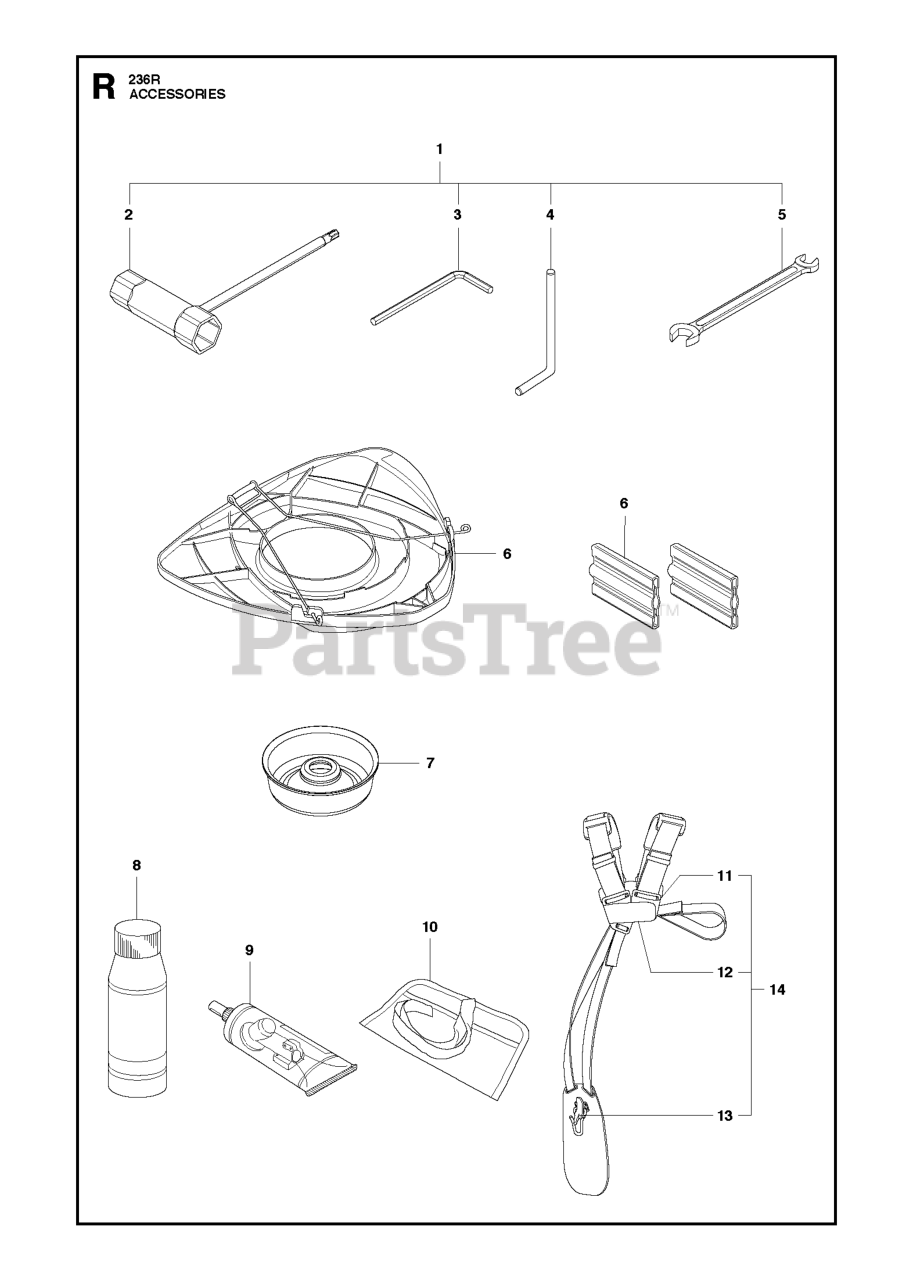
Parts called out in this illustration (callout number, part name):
5	WRENCH SPANNER
6	TRANSPORT GUARD
6	BAR GUARD
7	SUPPORT CUP
8	Air Filter Oil 1l.
9	BEVEL GEAR GREASE
13	HOOK, CPL.
14	HARNESS DUO
